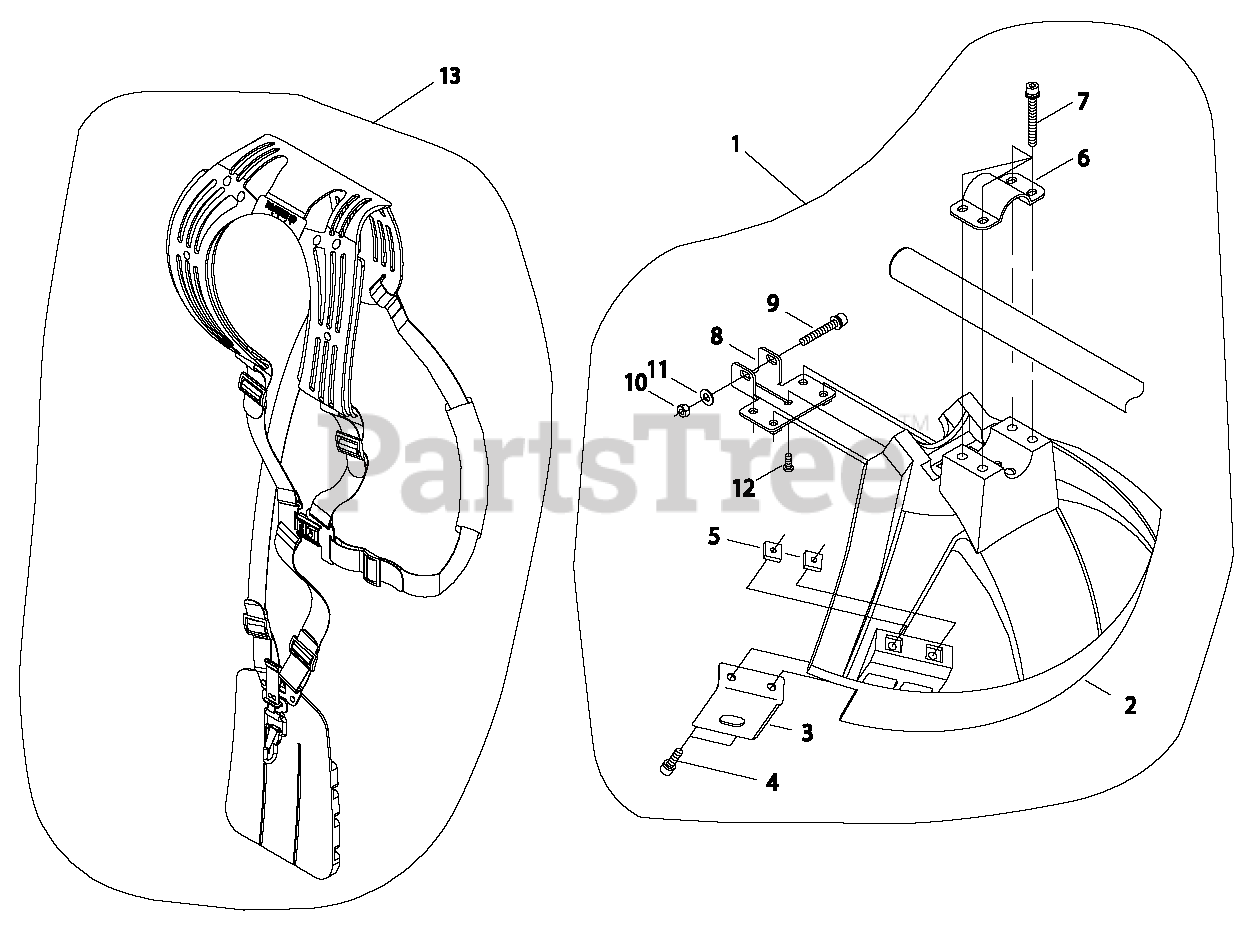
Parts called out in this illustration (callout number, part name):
1	DEBRIS SHIELD ASSY
2	SHIELD, DEBRIS
3	CUTTER
4	BOLT M5×16
5	NUT M5
6	CLAMP, UPPER
7	BOLT M5×45
8	CLAMP, LOWER
9	BOLT M6×40
10	NUT, HEX M6
11	WASHER
12	SCREW HILO 4×10
13	HARNESS ASSY
